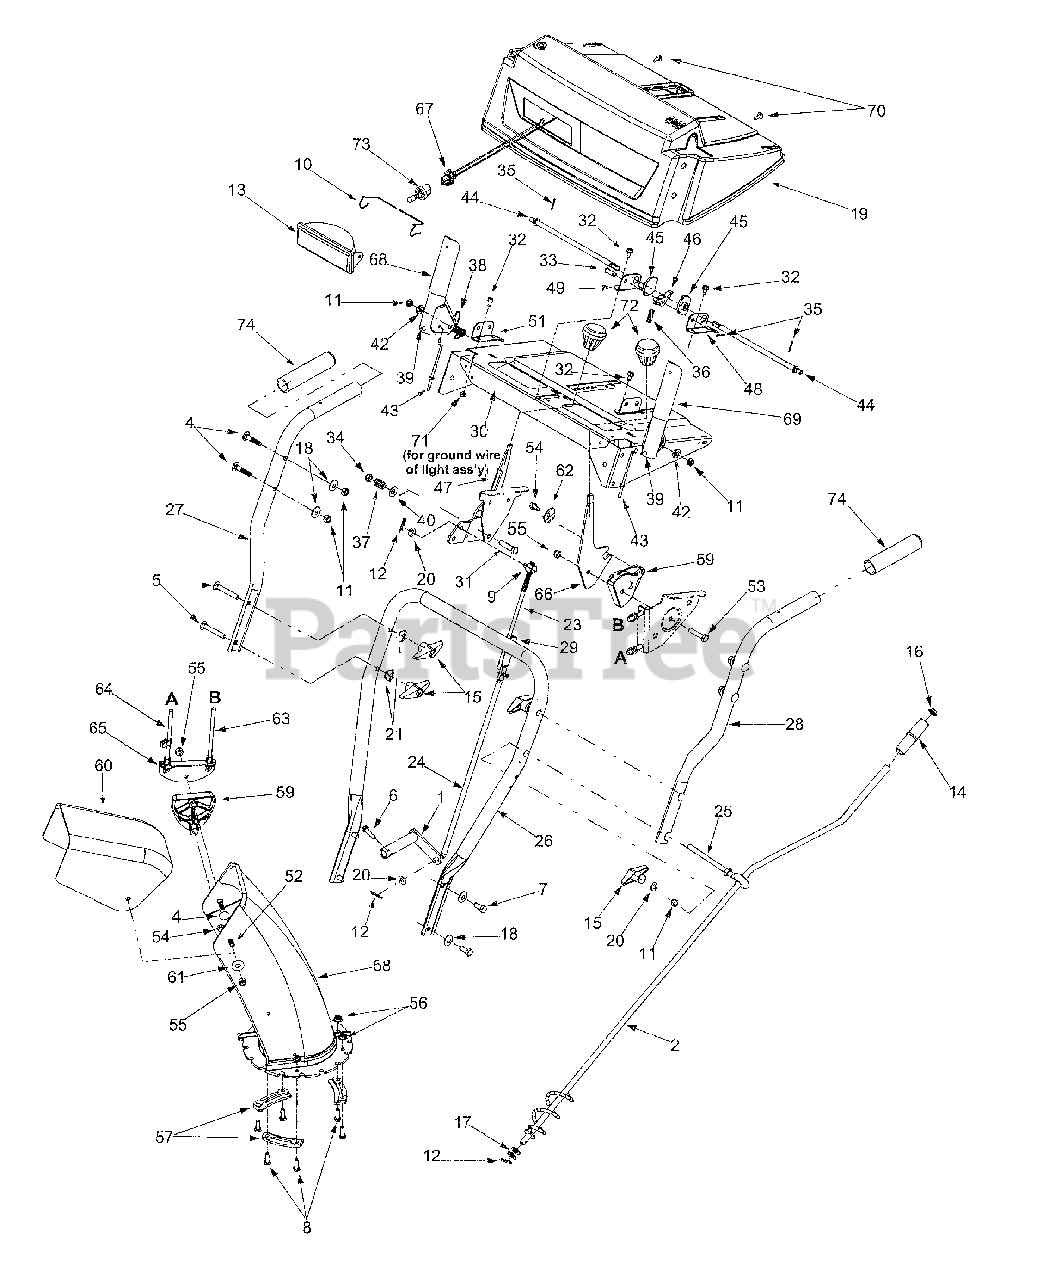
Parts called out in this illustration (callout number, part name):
1	Shift Arm Assembly
2	Chute Crank Ass'y
4	Carriage Bolt, 5/16-18 x 1.5
5	Carriage Bolt, 5/16 18 x 2.25
6	Self Tapping Screw, 1/4-20 x 1
7	Hex Cap Screw, 5/16-18 x .75
8	Hex Cap Screw, 1/4-20 x .75
9	Ferrule, 5/16-18 x .312
10	Headlamp Retainer
11	Hex Nut, 5/16-18
12	Internal Cotter Pin
13	Lens Assembly/Lamp Housing
14	Chute Crank Knob
15	Wing Knob, 5/16-18
16	Push Cap, 3/8
17	Flat Washer, .375 x .738 x .063
18	Bell Washer, .34 x .872
19	Handle Panel
20	Flat Washer, .344 x .688 x .065
21	Saddle Washer, .32 x .93
23	Upper Shift Rod
24	Lower Shift Rod
25	Eyebolt
25	Grommet
31	Hex Cap Screw, 3/8-24 x 1.5
32	Self Tapping Screw, 1/4-20 x.5
33	Clevis Pin
34	Jam Nut, 3/8-24
35	Cotter Pin .072 x 1.12
36	Compression Spring, .36 x 1.0
37	Comp. Spring, .39 x .6 x .88
38	Torsion Spring, .44 x .8
39	Rubber Bumper
40	Bell Washer, .401 x .87 x .063
42	Special Washer, .35 x .72 x. 13
43	Cable "Z" Fitting
44	Cam Rod
45	Cam Handle Lock
46	Handle Lock Pawl
47	Shift Handle
48	LH Handle Support Bracket
49	RH Handle Support Bracket
51	RH Handle Support Bracket
52	Carriage Bolt, 5/16-18 x .75
53	Hex Cap Screw, 5/16-18 x 1.5
54	Screw, 1/4-14 x .625
55	Hex Lock Nut, 5/16-18
56	Hex Flange Lock Nut, 1/4-20
57	Lower Chute Flange Keeper
58	Lower Chute
59	Chute Tilt Cable Guide
60	Upper Chute
61	Washer, 5/16
62	Special Washer, .28 x 1.2 x .06
63	Chute Deflector Control Cable
64	Chute Deflector Cable w/ Clip
66	Chute Tilt Handle
67	Halogen Light Harness
68	RH Engagement Handle Ass'y
69	LH Engagement Handle Ass'y
70	Special Screw, #10-16 x .625
71	Hex Sems Nut, 1/4-20
72	Plastic Knob
73	Halogen Lamp, 12-volt, 27 Watt
74	Handle Grip
